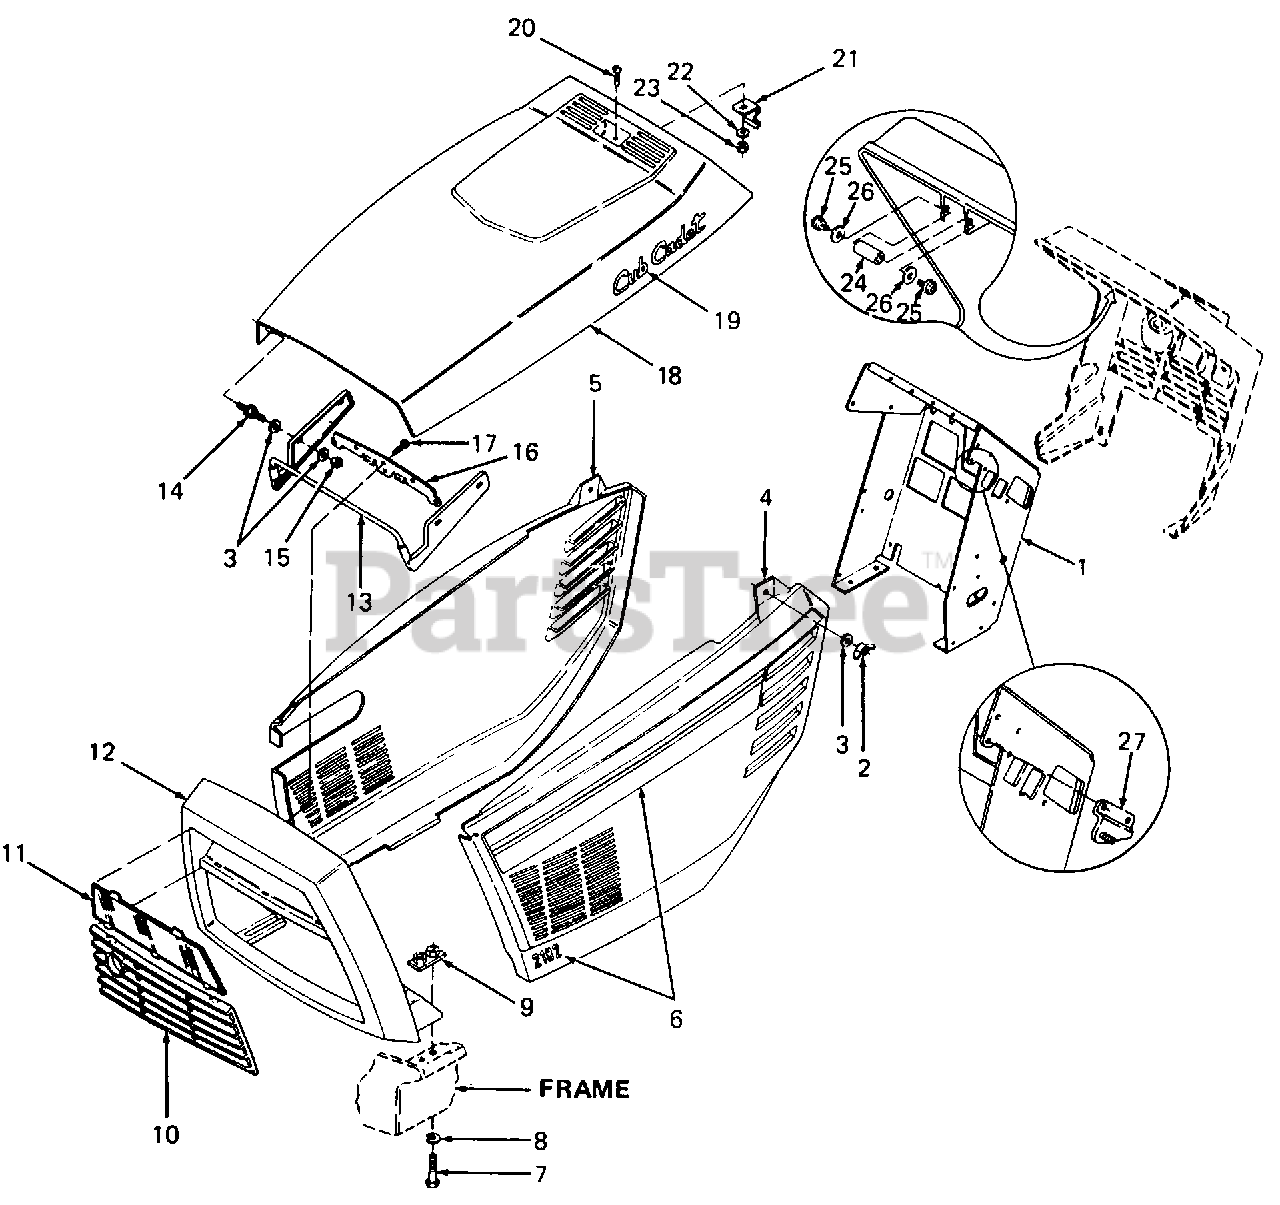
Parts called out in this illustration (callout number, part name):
3	Washer, Flat, .251 X .62 X .052 Thk
4	Panel, LH Side w/Slots
5	Panel, RH Side w/Cutout & Slots
6	Graphics Kit, LH Side Panel
7	Screw, Hex Cap, 5/16-18 X 1.0 Lg GR5
8	Washer, Lock, 5/16
9	Retainer, Grille Housing
10	Grille, Insert
11	Grille, Lens
12	Grille w/Label
15	Nut, Hex Patch Lock, 1/4-20
18	Hood
19	Graphic, Cub Cadet Script w/Studs
20	Screw, Truss Hd Mach, #8-32 X .38 Lg
21	Clip, Hood Latch
22	Washer, Flat, .16 X .38 X .045 Thk
23	Nut, Hex Keps, #8-32
24	Pin, Latch
25	Screw, Phillips Hd Truss Mach, 1/4-20 X .50 Lg
26	Washer, Flat, .285 X 1.25 X .060 Thk
